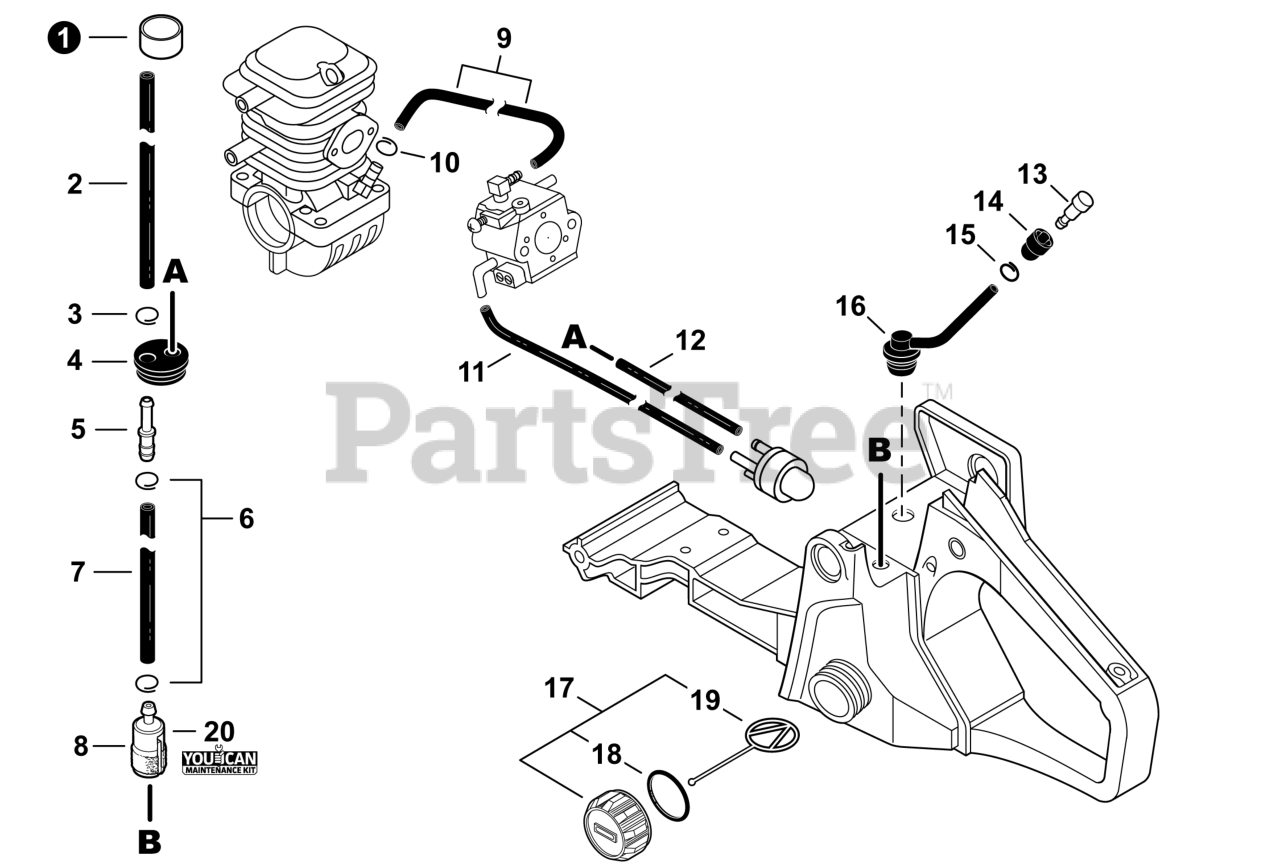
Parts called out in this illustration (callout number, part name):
1	TUBE 8x9x16
2	PIPE, FUEL - 3x5x182 - BLACK
4	GROMMET, FUEL
5	CONNECTOR, PIPE 5x3.5
7	PIPE, FUEL - 3x5x68 - BLACK
8	FILTER, FUEL
9	PIPE, PULSE 2.4x6x105
11	PIPE, FUEL 2.4x5x105 BLACK
12	PIPE, FUEL 2.4x5x200 BLACK
13	VENT ASSY
14	HOLDER, VENT
15	CLIP 6.5 MM
16	PIPE, VENT 3x6x65
17	CAP ASSY, FUEL
18	O-RING 22
19	CONNECTOR, CAP L= 60 MM
20	TUNE-UP KIT - YOUCANT
